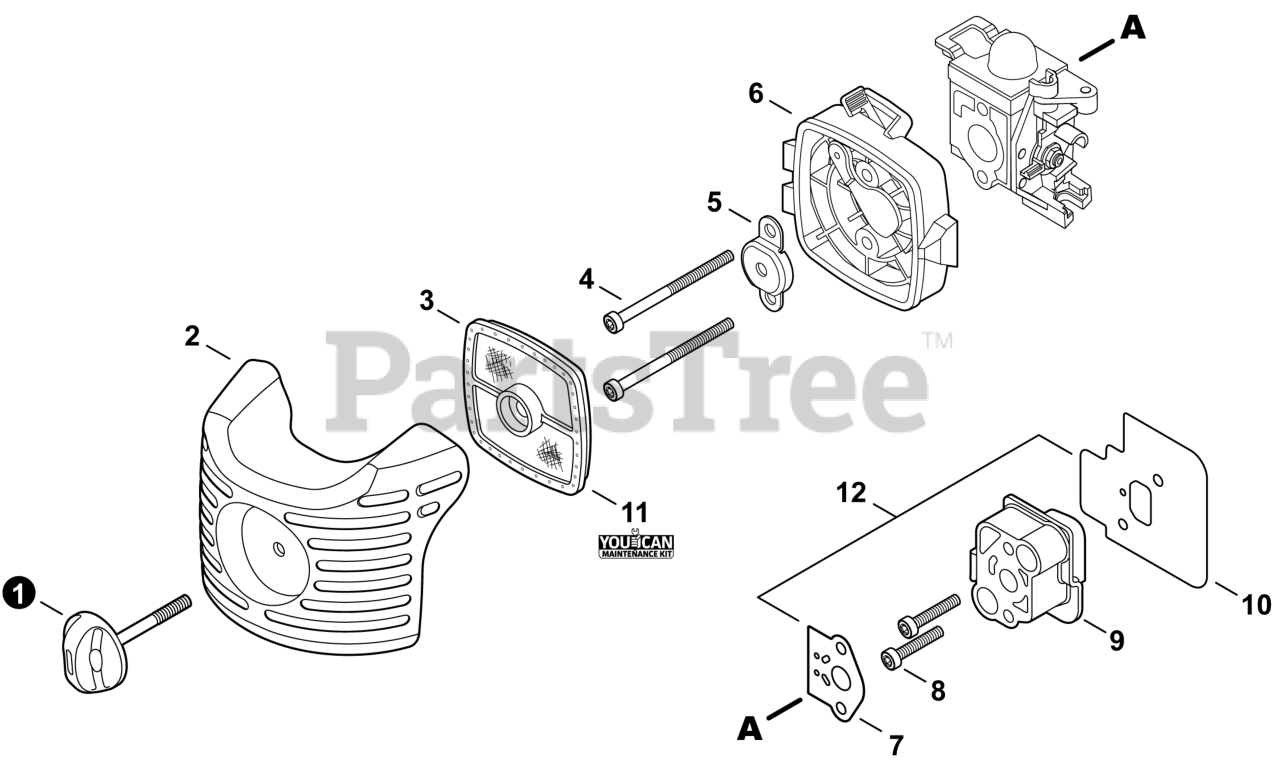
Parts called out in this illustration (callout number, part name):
1	THUMBSCREW
2	COVER, AIR FILTER
3	FILTER, AIR - DOUBLE LAYER
4	BOLT, TORX 5×65
5	PLATE, PREVENT
6	CASE ASSY, AIR FILTER
7	GASKET, INTAKE
8	BOLT, TORX 5×25
9	INSULATOR, INTAKE
10	HEAT SHIELD, INTAKE
11	TUNE-UP KIT - YOUCANT
12	GASKET KIT: ENGINE, INTAKE, EXHAUST
